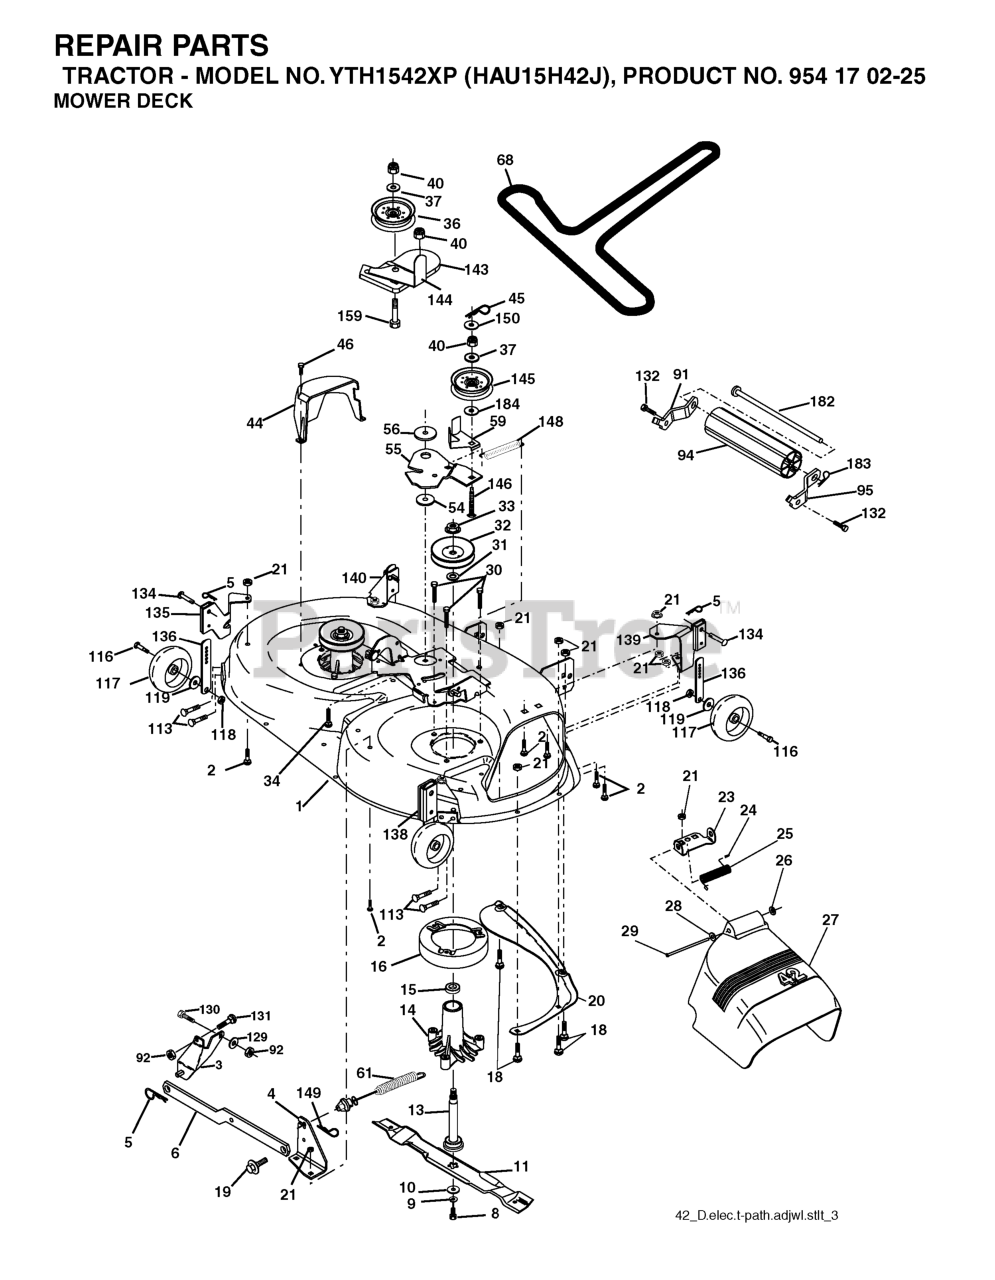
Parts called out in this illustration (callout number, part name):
1	MOWER DECK SHELL 42"
2	RP BOLT 5/16-18 X3/4 ZN/YEL GR
3	BRKT ASM SWAY BAR
4	BRACKET SWAY BAR 42" DECK
5	RETAINER-SPRNG RB
6	BAR SWAY DECK
8	BLADE BOLT
9	LOCKWASHER
10	WASHER.BLADE
11	42" HI-LIFT BLADE
13	SHAFT ASM VENT
14	HOUSING.MANDREL.VENTED (MACHD)
16	STRIPPER.MANDREL.ROUND.BLACK
18	BOLT
19	BOLT SHD 5/16-18
20	BAFFLE.VORTEX
21	LOCKNUT
23	BRKT, DEFL. MOWER
24	CAP-SLEEVE LT
25	SPRING TORSION
26	NUT PUSH M
27	SHIELD DEFLECTOR
28	Washer 11/32 x 5/8 x 16 Ga SD
29	ROD.HINGE
30	SCREW, WASHER HEAD
31	WASHER.SPACER.MANDREL
32	PULLEY MANDREL
33	NUT, FLG TOPLOCK 9/16"
34	BOLT.3/8-16X1.50
36	PULLEY.IDLER.FLAT
40	NUT LOCK FLG 3/8-16 UNC
44	GUARD MANDREL LH BLACK
45	RETAINER M
46	SCREW.1/4-20X5/8
55	ARM IDLER 42" MOWER LT/YT
56	SPACER RETAINER
59	GUARD TUV IDLER
61	SPRING EXT ELEC CLUTCH
68	V-BELT PRIMARY 42"
91	BRACKET ASM NOSEROLLER LH
92	NUT
94	NOSE ROLLER
95	BRACKET ASM NOSEROLLER RH
113	SCREW 5/16"
116	SHOULDER BOLT
117	WHEEL GAGE DONUT
118	LOCKNUT
119	WASHER.5/16.FLAT.STE.STD.
129	WASHER
131	BOLT D
132	SCREW, 3/8-16X3/4
134	RIVET.PIN.HEAD.YELLOW.
135	BRACKET ASM, WHEEL
136	BAR.ADJUST.WHEEL.ANTI.SCALP.BL
138	BRACKET.ASM.WHL.GA.R.RH.42".GR
139	BRACKET ASM, WHEEL
140	BRACKET ASM, WHEEL
143	BRACKET, ARM IDLER
144	KEEPER BELT 42" CLUTCH
145	PULLEY.IDLER.FLAT.PLATED
146	BOLT CARRIAGE IDLER
148	IDLER RETURN SPRING
149	SPRING.RETAINER.YELLOW.ZINC
182	ROD ROLLER NOSE STANDARD
183	SPRING RETAINER
184	WASHER
